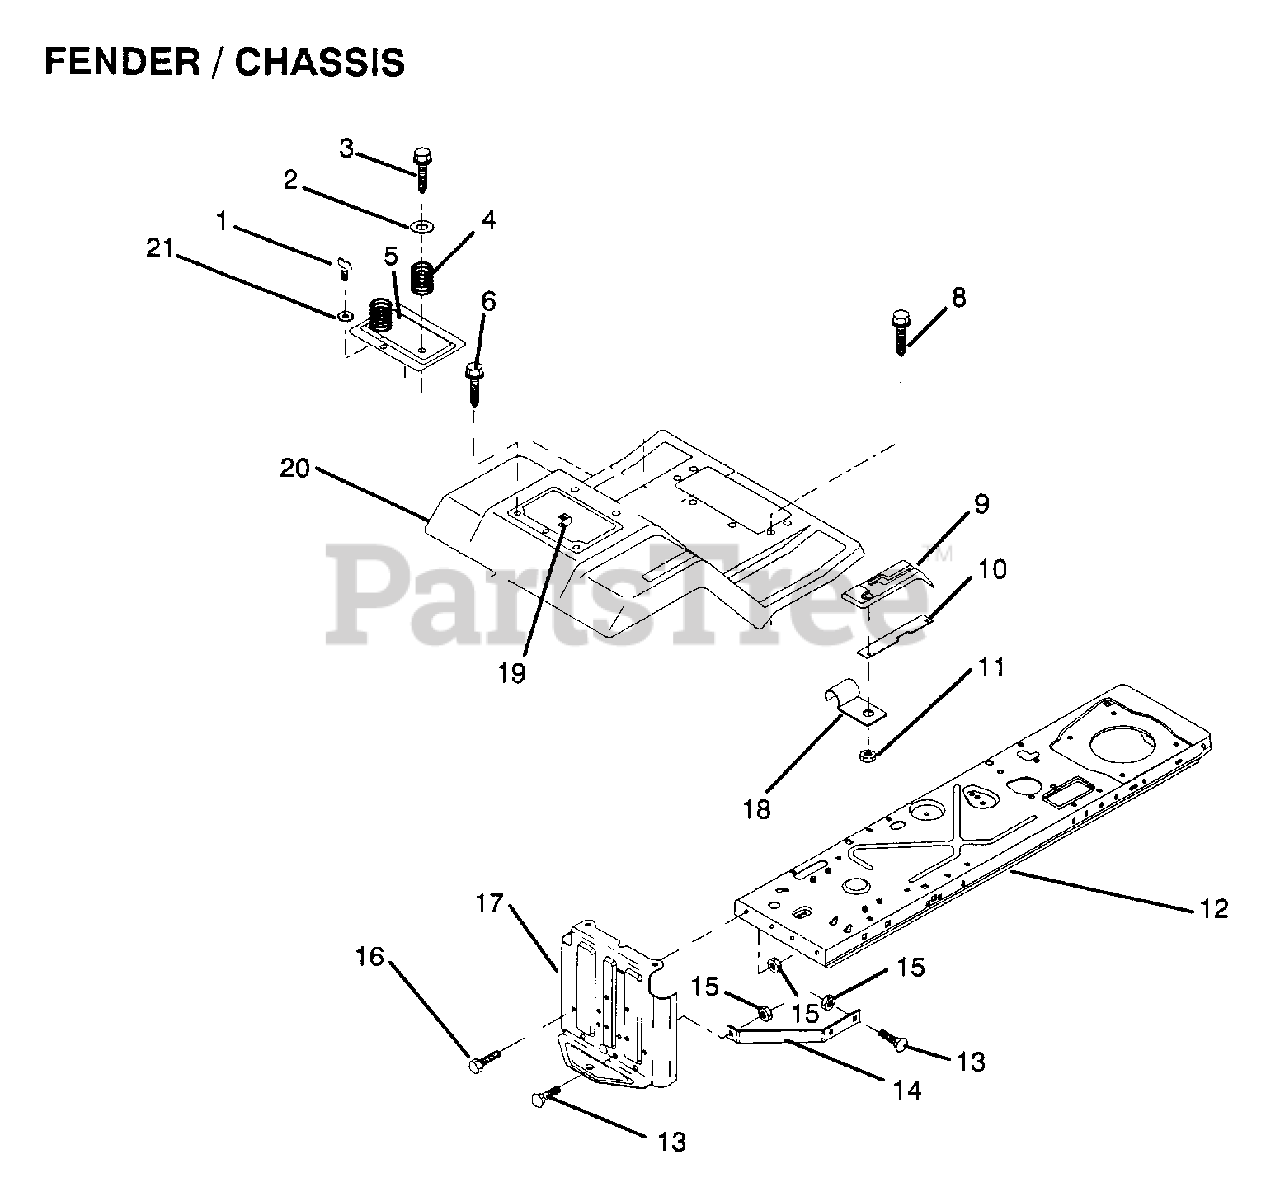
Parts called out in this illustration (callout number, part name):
1	STUD.1/4.TURN
2	WASHER
3	SCREW
4	SPRING COMPRESSIO
6	SCREW LT
7	PAD FOOTREST
8	SCREW
9	CONSOLE SHIFT
11	NUT
12	FRAME ASS'Y
13	BOLT
14	"BRACE,DRAWBAR "
16	BOLT
17	DRAWBAR
18	"CLIP,INSULATOR"
19	RECEPTACLE LT
20	FENDER/FOOTREST
21	RETAINER LT
